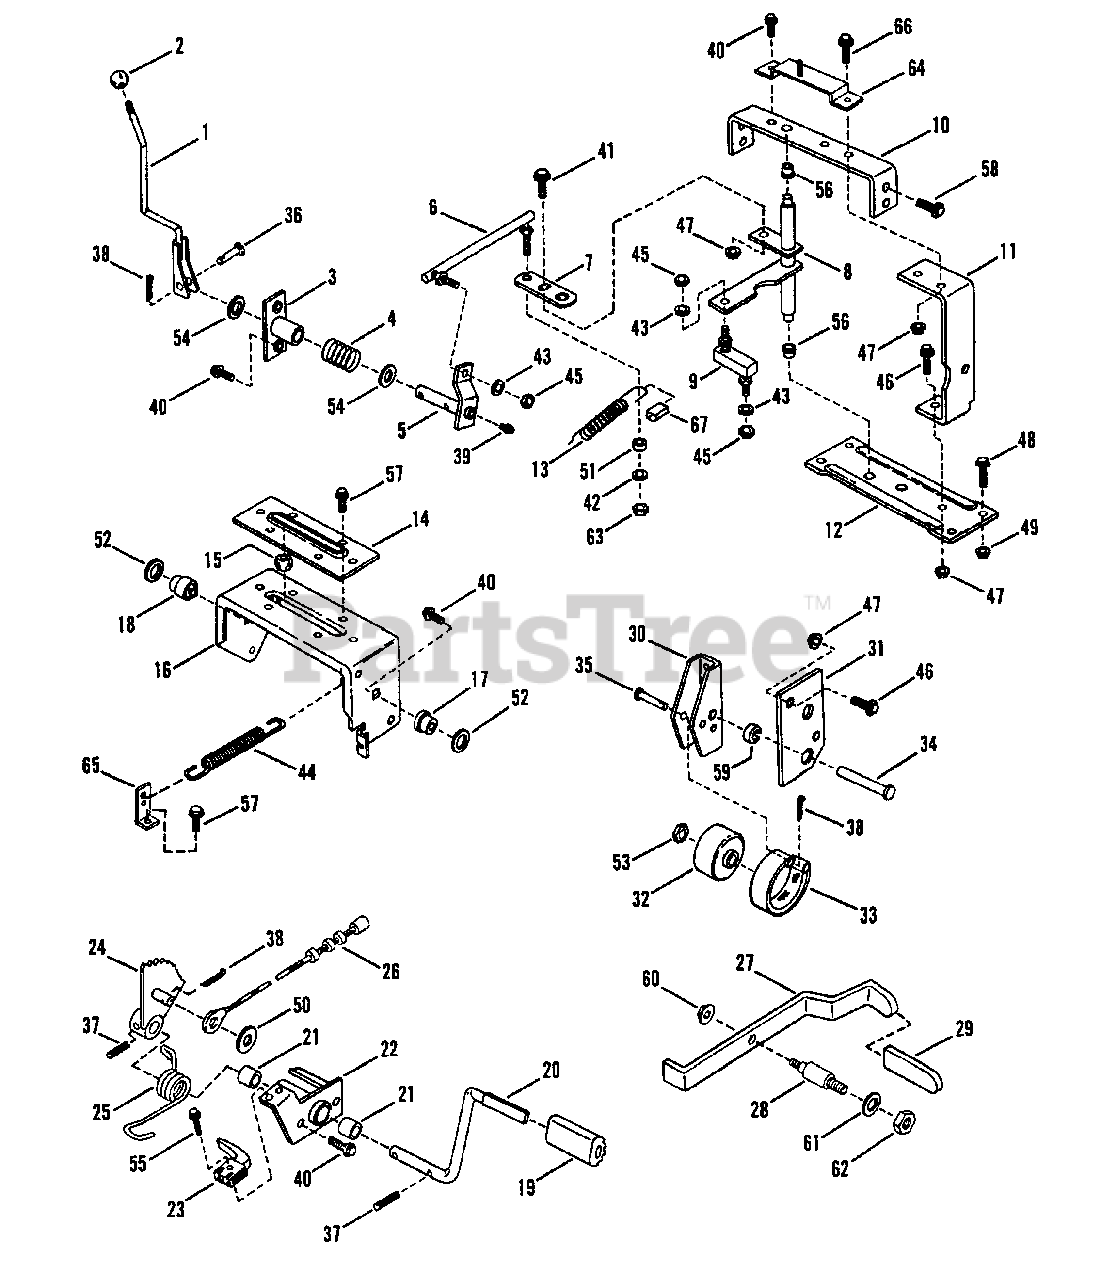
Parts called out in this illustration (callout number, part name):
1	SHIFTER, Transmission
2	KNOB, Shifter
3	PIVOT, Shift
4	SPRING, Shift Detent
5	ARM, Shifter
6	LINK, Shift-Long (8.53")(No longer available)
7	ARM, Shift Adjusting
8	ARM, Shift
9	LINK, Shift-Short
10	STRAP, Upper Cross
11	STRAP, Brake Pivot Support (No longer available)
12	STRAP, Lower Cross (No longer available)
13	SPRING, Reverse Assist
14	RETAINER (PLATE), Clutch Yoke Bushing
15	BUSHING, Clutch Ball
16	YOKE, Clutch
17	BUSHING, Yoke Pivot-Short
18	BUSHING, Yoke Pivot-Long
19	PAD, Pedal
20	PEDAL, Clutch Brake
21	BEARING, Sleeve
22	BRACKET, Pedal Pivot
23	SWITCH, Clutch Interlock
24	ARM, Clutch/Brake
25	SPRING, Clutch/Brake
26	CABLE, Clutch/Brake 36"
27	LEVER, Parking Brake
28	STUD, Parking Brake
29	SLEEVE, Parking Brake
30	LEVER, Brake Pivot
31	SUPPORT, Brake Pivot
32	DRUM, Brake
33	BAND, Brake
34	PIN, 3/8 x 2-9/16" Clevis
35	PIN, 1/4 x 1-13/16" Clevis
36	PIN, 3/8 x 1-1/4" Clevis
37	PIN, 3/16" x 1-1/4" Roll
38	PIN, 3/32 x 3/4" Cotter
39	FITTING, Lube
40	SCREW, 5/16-18 x 5/8" Hex Flange Self-Tap
41	BOLT, 5/16-18 x 5/8" Hex Flange Lock
42	WASHER, 5/16 SAE
43	WASHER, 5/16 Split Lock
44	SPRING
45	NUT, 5/16-24 Hex
46	BOLT, 5/16-18 x 3/4" Hex Flange Lock.
47	NUT, 5/16-18 Hex Flange Lock, Grade 5
48	BOLT, 3/8-16 x 3/4" Hex Flange Lock
49	NUT, 3/8-16 Hex Flange Lock
50	WASHER, 3/8 SAE Flat
51	ROLLER, Shift Arm
52	WASHER, Shim
53	JAM-NUT, 5/8-18
54	WASHER, Thrust
55	SCREW, #10-24 x 1" Self-Tap
56	BEARING, Nylon
57	SCREW, 1/4-20 x 1/2" Hex Flange Self-Tap
58	SCREW, 3/8-16 Hex Flange Self-Tap
59	RING
60	NUT, 1/4-20 Small Flange Lock
61	WASHER, 3/8 Internal Tooth Lock
62	NUT, 3/8-16 Hex, Grade 5
63	NUT, 5/16-24 hex Center Lock
64	ASSEMBLY, Bracket
65	CLIP, Spring Attach
66	BOLT, 5/16-18 x 1" Hex Flange Lock
67	CLIP, Spring Retainer
